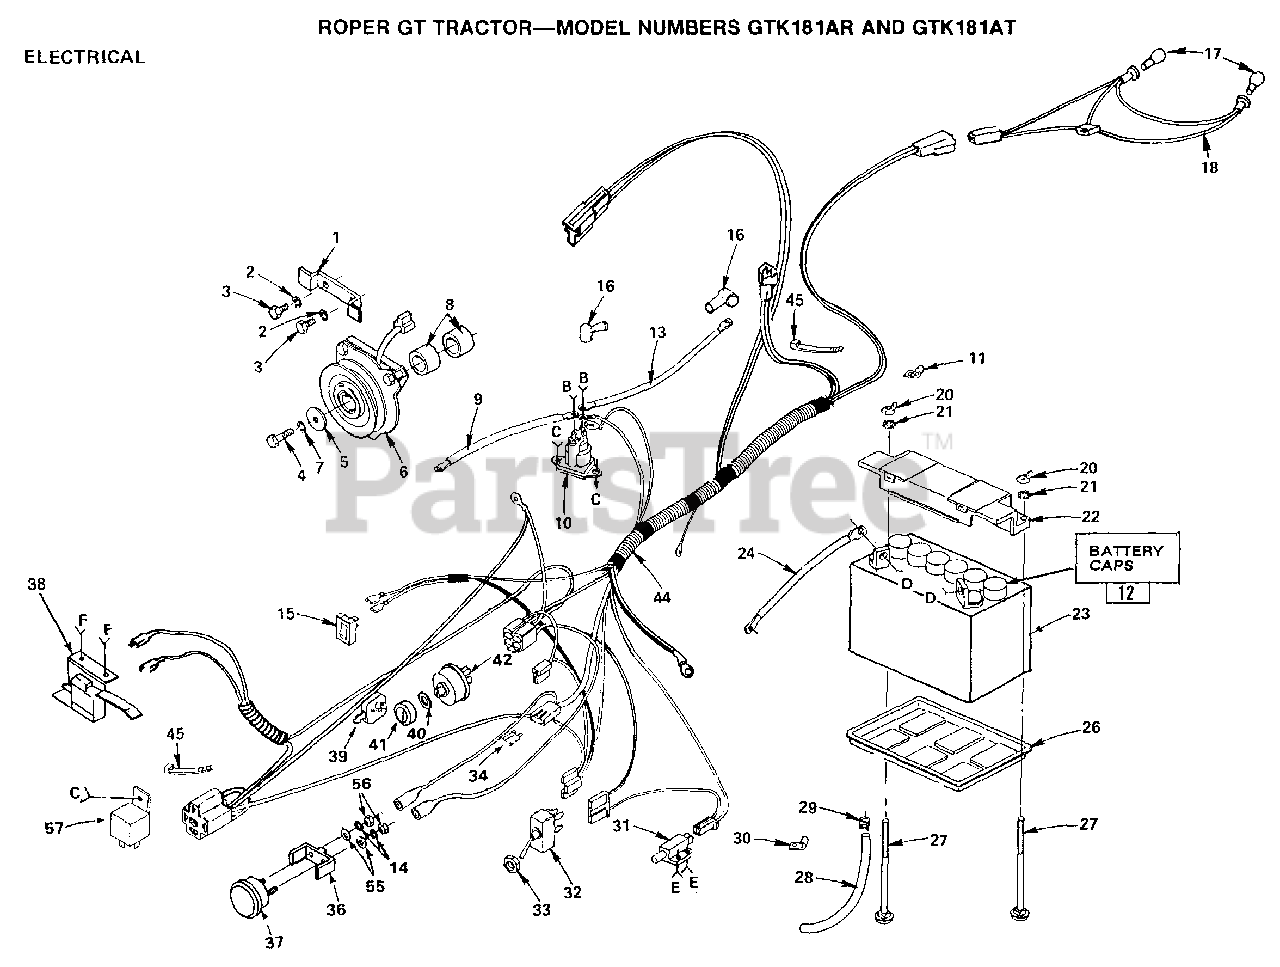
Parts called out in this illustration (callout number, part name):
2	LOCKWASHER
3	BOLT
5	WASHER T
6	CLUTCH.ELECTRIC.T
7	LOCKWASHER
8	SPACER-CLUTCH GT
9	CABLE-BATTERY T
12	BATTERY CAPS
15	SWITCH LT
18	HARNESS T
21	LOCKWASHER GT
24	CABLE T
26	"TRAY T, BATTERY"
27	BOLT
29	HOSE CLAMP T
30	CLIP GTV
31	SWITCH-INTER. GT
32	SWITCH.PTO.T
33	HEX NUT T
34	FUSE-30 AMP
37	AMMETER T
45	WIRE TIE
55	WASHER
57	RELAY ASSY T
